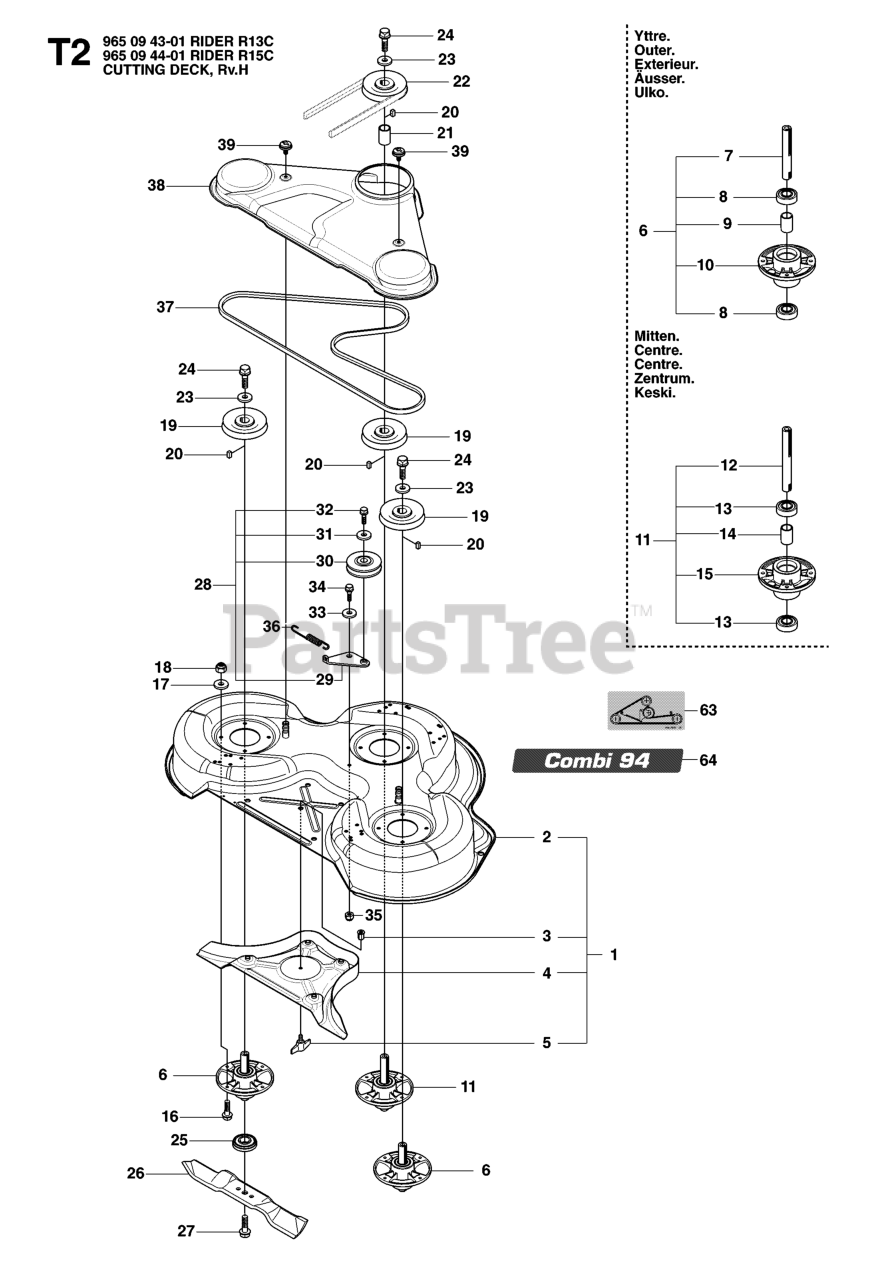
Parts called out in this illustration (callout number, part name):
4	PLUG C93 & C94
6	RP SPINDLE ASSY
10	BEARING HOUSING
15	BEARING HOUSING
17	WASHER BRB 8.4X17
18	LOCKNUT M8
21	SPACING SLEEVE
25	BLADE BRACKET
30	PULLEY
33	WASHER
35	LOCKNUT M8
37	BELT A69
38	BELT COVER C93 & C94 GREY
